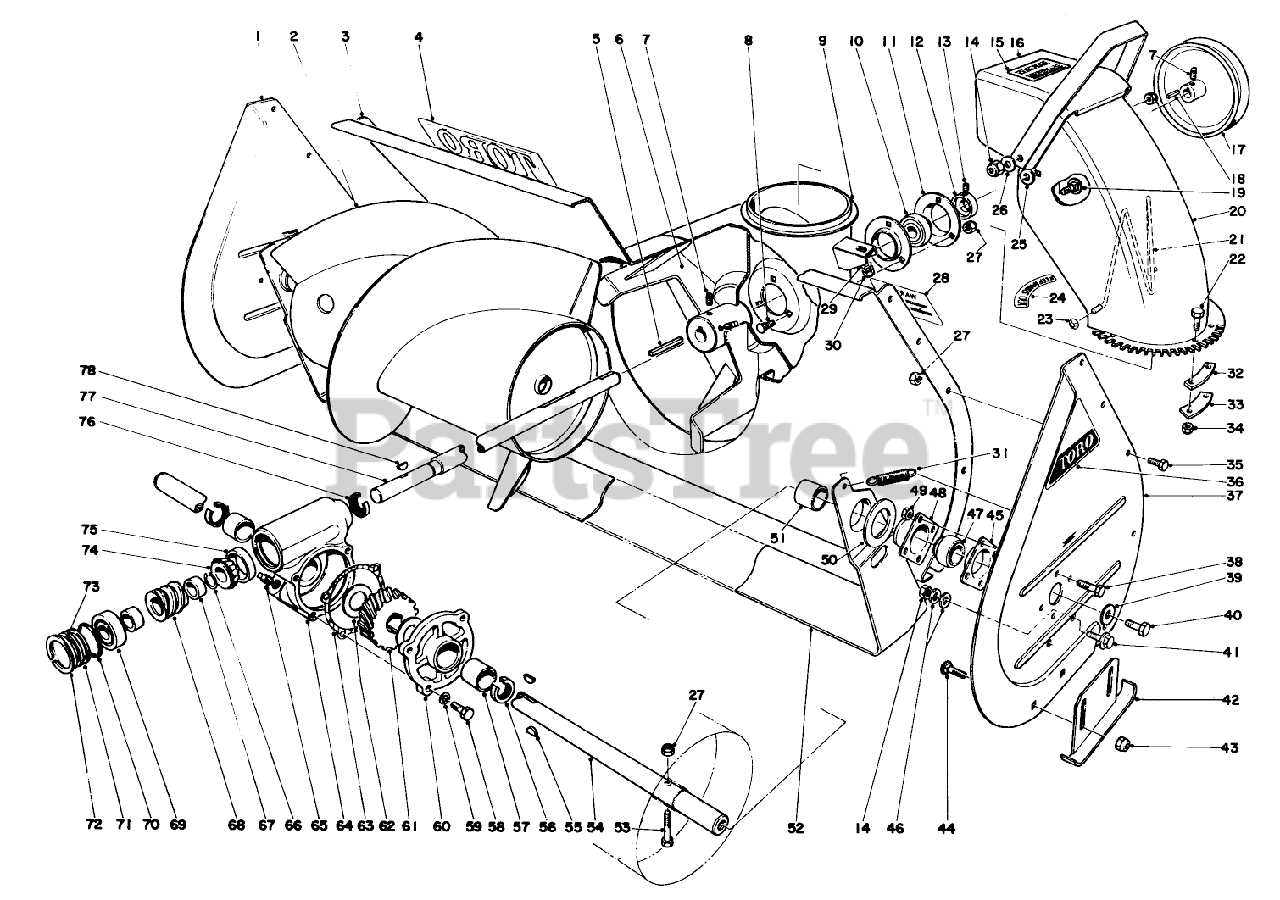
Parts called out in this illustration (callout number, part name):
1	Side Plate
2	Auger R.H.
3	Auger Housing (Incl. Ref. #28)
4	Decal
6	IMPELLER ASM
7	SCREW-SET, SQH
8	BOLT-CARR
9	SUPPORT B
10	BALL BRG W/COLLAR
11	BRG FLANGE
12	EXT LOCKING COLLAR
13	SCREW-HSH
14	NUT-LOCK, CONE
15	Decal
16	Def vector (Incl. Ref. #15)
17	1/2 X 9.5 DIA PULLEY
18	SQUARE KEY
19	SCREW-CARR
20	Upper Chute (Incl. Ref. #24)
21	WIRE-CHUTE
22	SCREW-HWH
23	NUT-PUSH
24	Decal
25	WASHER-RUBBER
26	WASHER-BELLEVILLE
27	NUT-LOCK, CONE
28	Decal
29	WASHER-LOCK
30	NUT-LOCK, CONE
31	SPRING-TENSION
32	UPPER CHUTE TAB
33	CHUTE TAB SPACER
34	Nut
35	SCREW-HH
36	AUGER SIDE PLT DECAL
37	Side Plate L. H.
38	SCREW-HH
39	WASHER
40	SCREW-HH
41	SCREW-HHF
42	Skid
43	NUT-HHF, WHIZ
44	SCREW-CARR
45	BEARING-FLANGE, REAR
46	WASHER-FLAT
47	BEARING
48	BEARING-FLANGE, FRONT
50	SCRAPER BLADE SPACER
51	SPACER
52	SCRAPER BLADE 32" R
53	Auger Bolt
54	32 AUGER SHAFT
55	KEY-WOODRUFF
56	SEAL-OIL
57	Bushing
58	SCREW-HH
59	WASHER-LOCK
60	Gear Box Cover (Incl. Ref. #57)
61	GEAR-WORM, 27T
62	WASHER-THRUST
63	Gasket
64	Gear Box (Incl. Ref. #57 & 75)
65	PLUG-PIPE, SQH
66	RETAINER RING
67	Spacer
69	.750 BALL BEARING
70	O-RING
72	INTRNL RETAINING RING
74	3/4 ROLLER BRG CONE
75	1.750 ROLLER BRG CUP
76	SEAL-OIL
77	Shaft Worm
78	KEY-WOODRUFF
